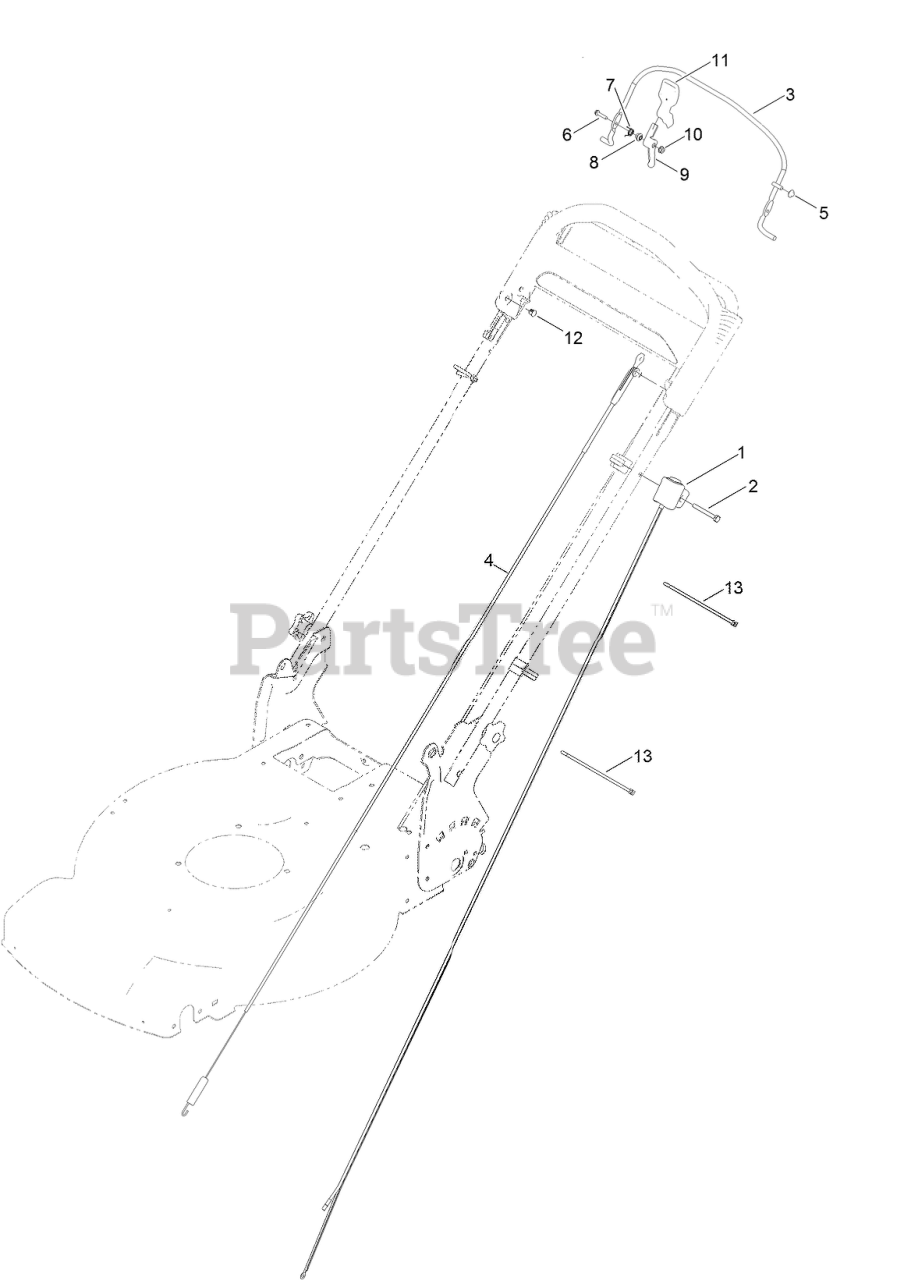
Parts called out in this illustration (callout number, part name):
1	SWITCH HOUSING ASM
2	SCREW-HH
3	BAIL-BRAKE
4	CABLE-BRAKE
5	NUT-SPEED
6	SCREW-HWH
7	SPRING-TORSION
8	SPACER
10	NUT-HEX FLANGE
12	PLUG-DOME
13	TIE-CABLE
